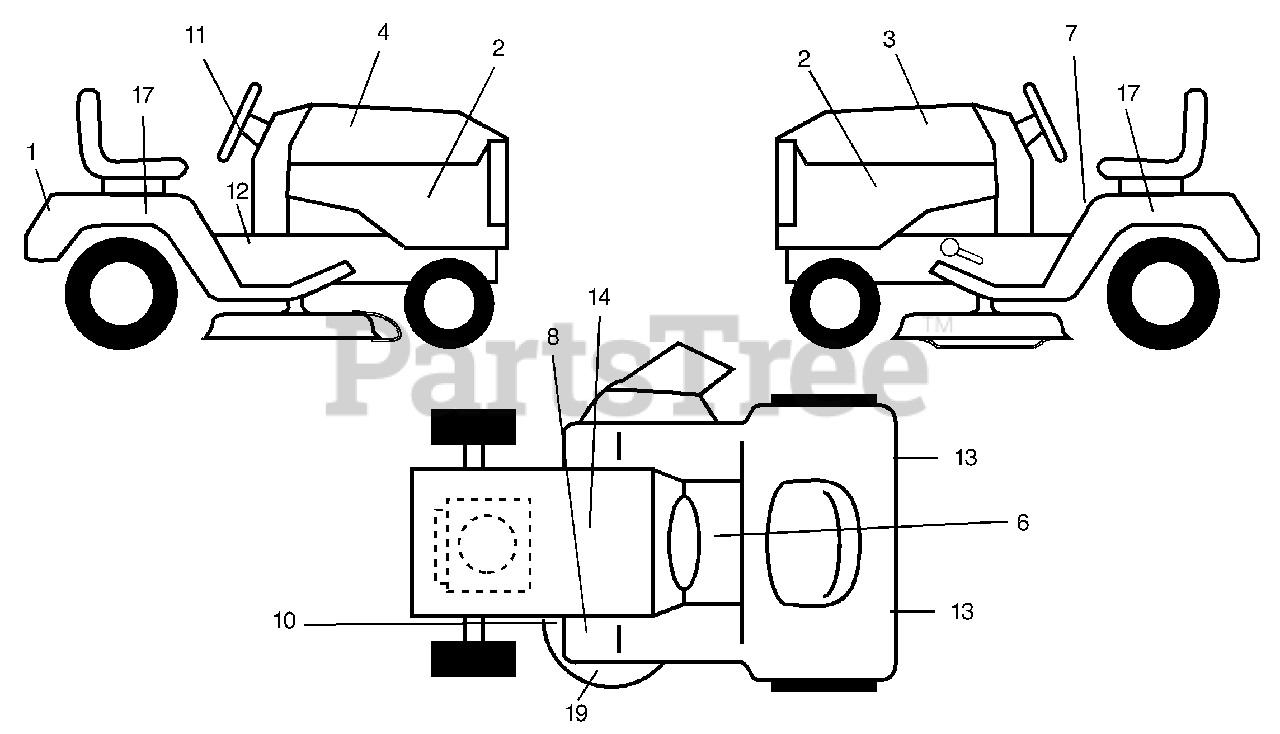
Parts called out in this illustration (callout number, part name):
1	Decal Fender
2	Decal Side Panel
3	Decal Hood LH
4	Decal Hood RH
6	Decal Parking Brake
7	Decal Danger Fender English
8	Decal Clutch/brake English
10	Decal V-Belt Sch
11	Decal Steering
12	Decal Oper s DL Eng
13	Reflector Taillight
14	Decal, Btry Dngr/Psn
17	Decal Fender Side
